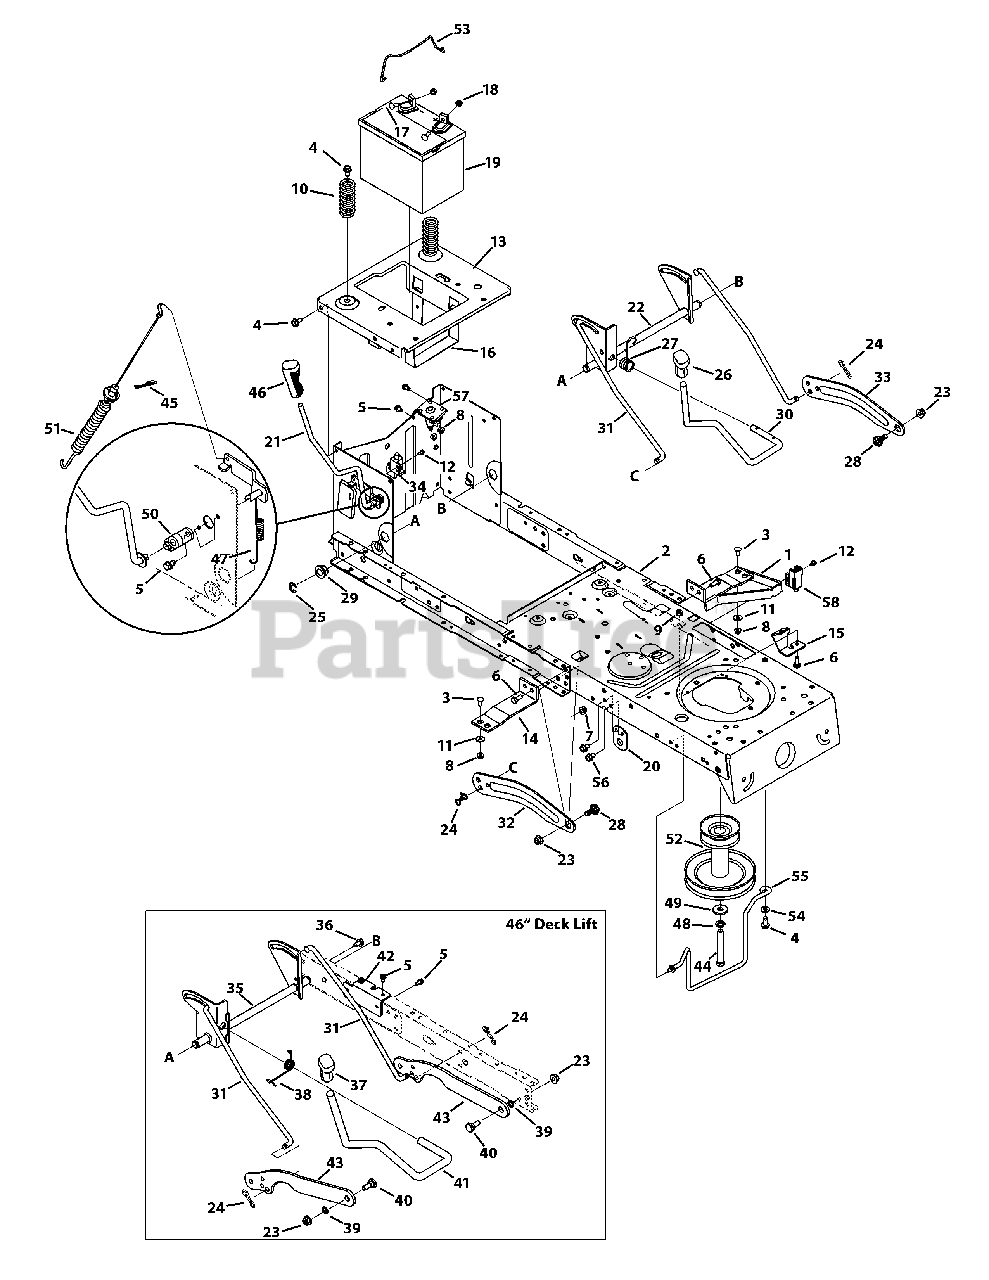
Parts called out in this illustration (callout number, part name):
1	Support Bracket - Powder Black
1	Support Bracket - Black Jack
2	Frame Assembly - Powder Black
2	Frame Assembly - Black Jack
3	Screw Carriage, 1/4-20 x .62
4	Screw 5/16-18 x .750
5	Screw, 1/4-20 x .500
6	Hex Screw, 5/16-18 x .75
7	Flangelock Nut, 5/16-18
8	Flangelock Nut, 1/4-20
9	Hexlock Nut, 5/16-18
10	Compression Spacer, 1.28 x 3.125
11	Flat Washer, .28 x .74 x .063
12	Shoulder Spacer, 10-32 x .500
13	Seat Frame Bracket - Powder Black
13	Seat Frame Bracket - Black Jack
14	Running Board Bracket
15	Support Frame Bracket
16	Battery Bracket
17	Hex Head Flange, 1/4-20 x .75
18	Sems Nut, 1/4-20
19	230 CCA Battery
20	Support Bracket
21	PTO Handle Assembly
23	Flangelock Nut, 3/8-16
24	Bow-tie Cotter Pin
25	E Ring
26	Handle Grip, 1/2
27	Torsion Spring
28	Shoulder Bolt, 3/8-16 x .625 x 1.75
29	Hex Flange Bearing
30	Deck Lift Handle 38" deck
30	Deck Lift Handle 42" deck
31	Lift Rod
32	38/42" Lift Arm, RH - Powder Black
32	38/42" Lift Arm, RH - Black Jack
33	38/42" Lift Arm, LH - Powder Black
33	38/42" Lift Arm, LH - Black Jack
34	Switch Interlock
35	Lift Assembly, 46" deck
36	Screw, 5/16-18 x .625
37	Handle Grip, 5/8
38	Torsion Spring Handle, 46" deck
39	Flat Washer, .385 x .62 x 0.63
40	Shoulder Bolt, 3/8-16 x .500 x .270
41	46" Lift Handle
42	Frame Brace Bracket
44	Hex Screw, 7/16-20 x 3.25, 38/42" deck
45	Click Pin
46	Handle Grip, 3/8
47	PTO Spring Extension
48	Regular Duty Washer Lock, 7/16
49	Flat Washer, .450 x 1.250 x .164
50	PTO Bearing
51	Deck Engage Cable
52	Engine Pulley, 3.39 x 6.12, 38/42"
53	Battery Hold Down Rod
54	Flat Washer, .406 x .875 x .059
55	38" Belt Keeper
55	42" Belt Keeper
56	Screw, 5/16-180 x .625
57	12V Solenoid
58	Screw Mount Interlock Switch
